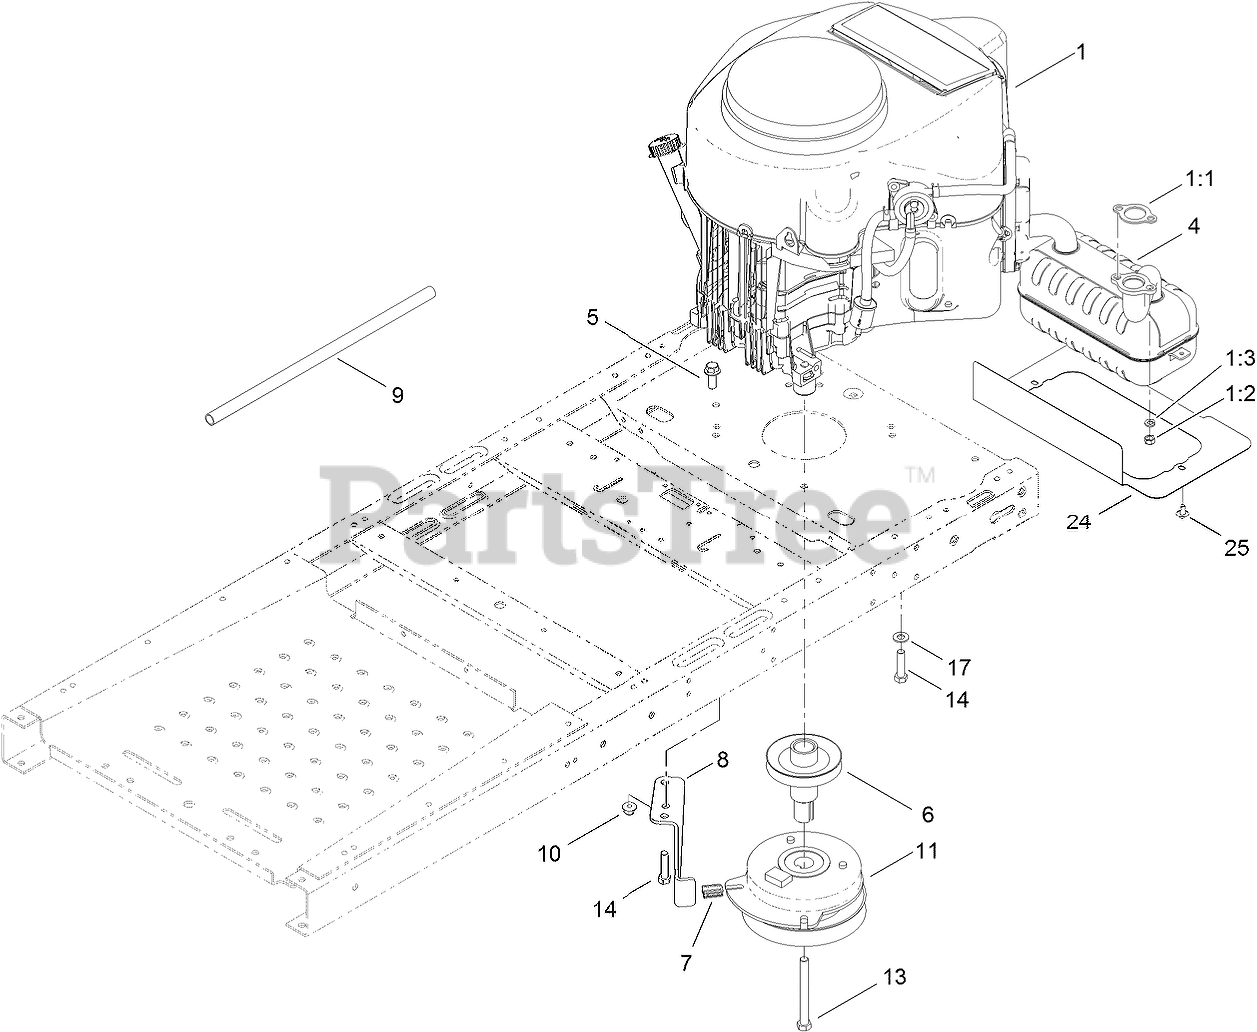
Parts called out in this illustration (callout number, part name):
1:1	GASKET-EXHAUST
1:3	WASHER-LOCK
4	MUFFLER-KAWASAKI
5	SCREW-HHF
6	PULLEY-ENGINE
7	ISOLATOR-CLUTCH
8	STOP-CLUTCH
9	TUBE-DRAIN, OIL
10	NUT-HF, NI
11	CLUTCH-ELECTRIC, PTO
13	Screw-HH
14	BOLT-HH
17	WASHER-FLAT
24	SHIELD-HEAT
25	SCREW-HHFTF
